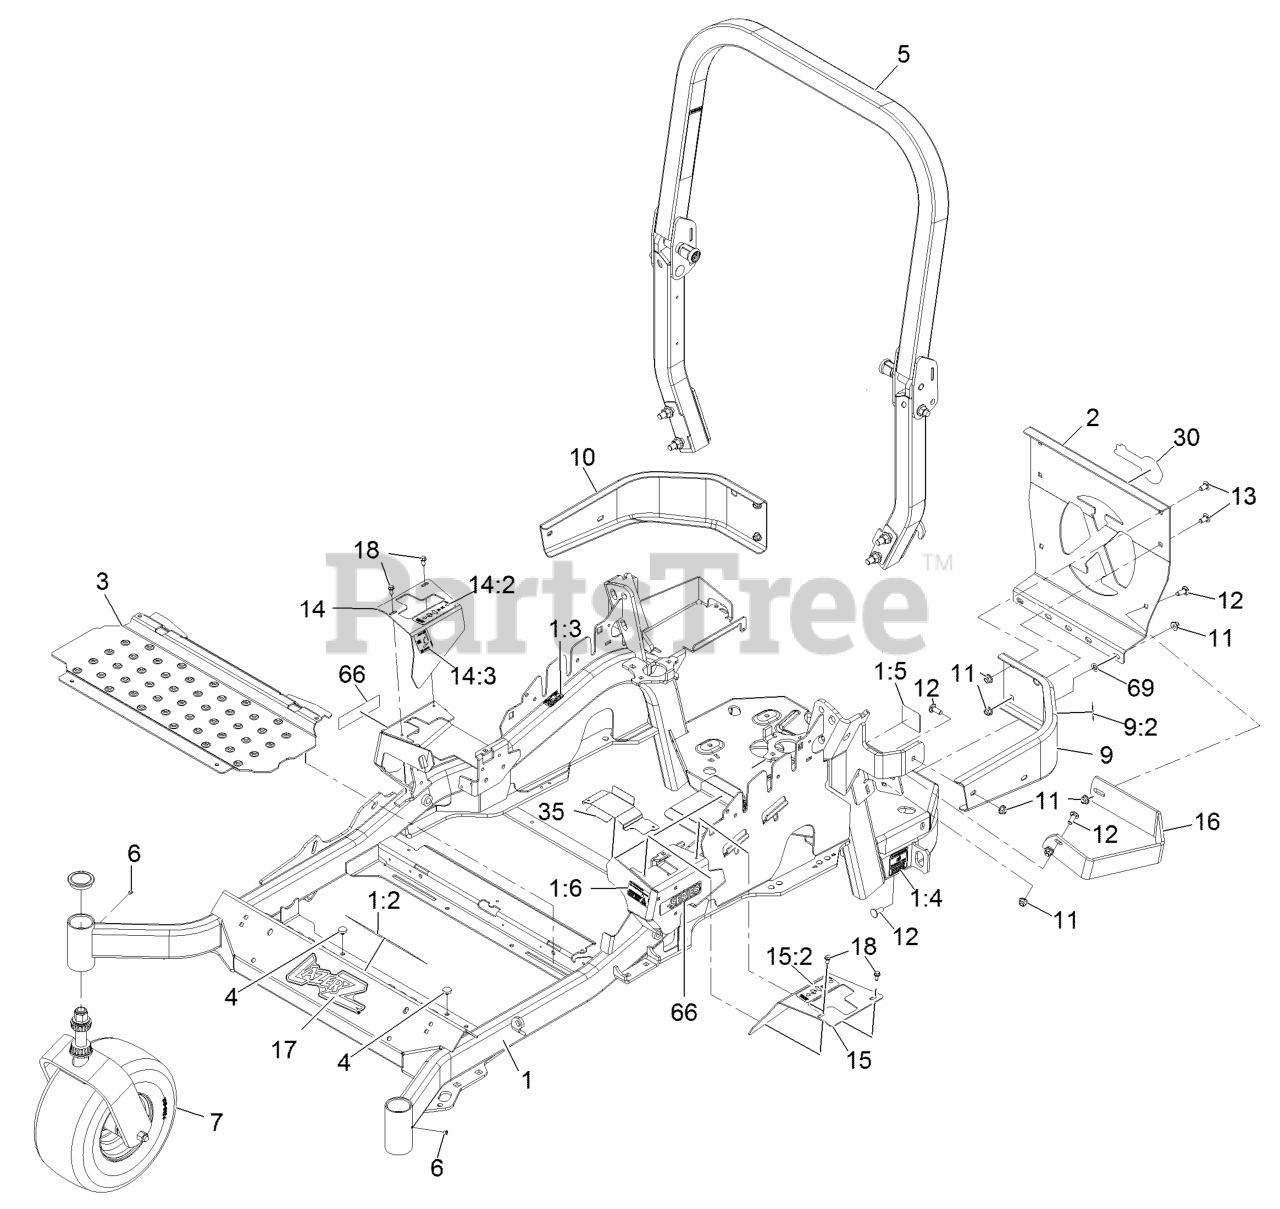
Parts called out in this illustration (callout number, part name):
1	MAINFRAME ASM
1:2	DECAL-SLOPE
1:3	DECAL-CAUTION
1:4	DECAL-BELT DRIVE
1:5	DECAL-SPARK ARRESTER
1:6	DECAL-FUEL FILL
2	PLATE,REAR GUARD
5	ROPS ASM
7	Caster Wheel Asm
9	LH BUMPER ASM
9:2	DECAL-CAUTION
10	BUMPER-RH
11	NUT-HF, NI
12	SCREW-CARR
13	SCREW-CARR
14	RH MOTION CONTROL COVER ASM
14:2	DECAL-MOTION CONTROL
14:3	DECAL-PARK BRAKE
15	LH MOTION CONTROL COVER ASM
15:2	DECAL-MOTION CONTROL
17	DECAL,LAZER MODEL
18	SCREW-HWH
35	GUARD-BELT
66	DECAL-E-SERIES
69	NUT-PUSH
